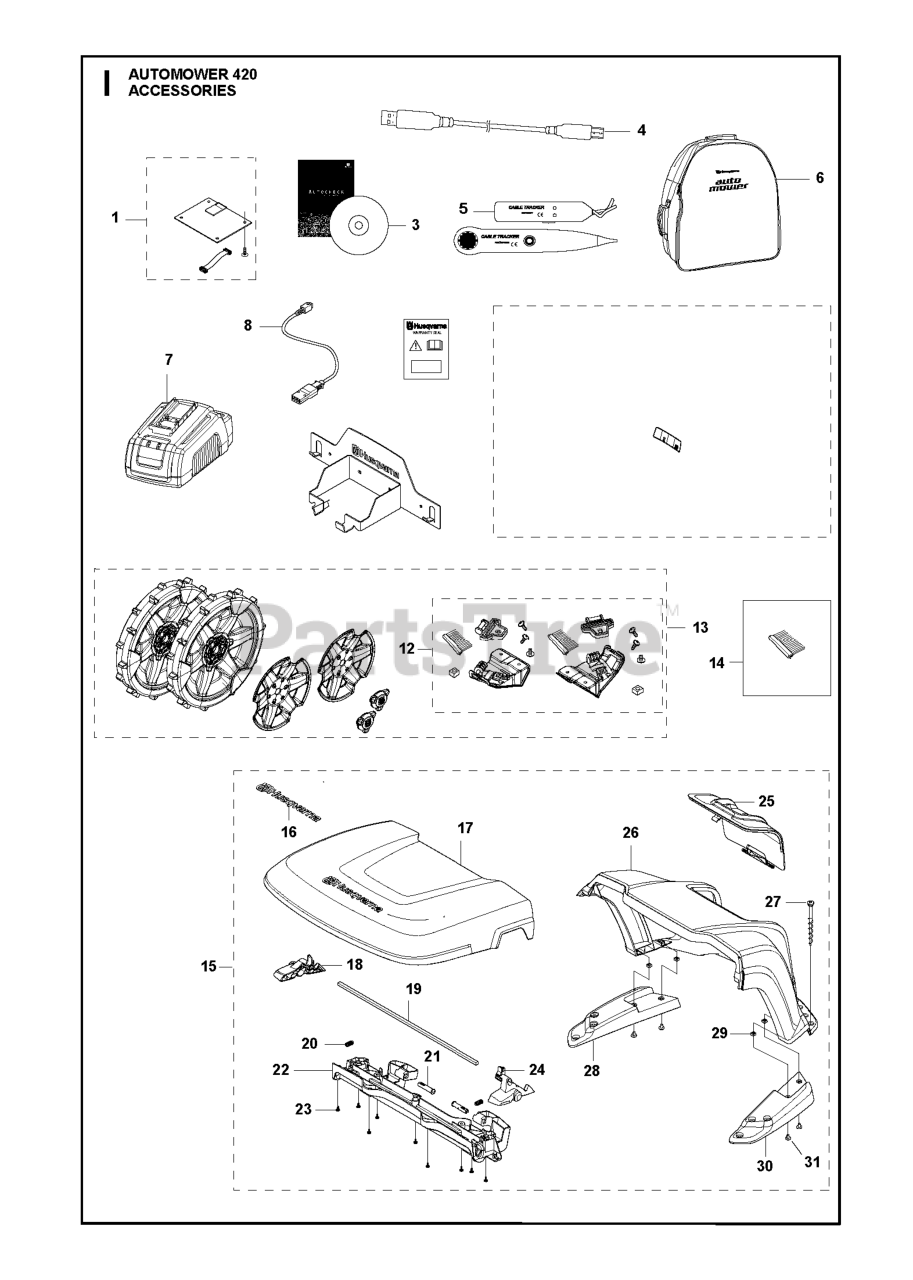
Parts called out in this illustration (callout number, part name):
1	CONNECT MODULE 315 / 430X
3	DVD AUTOCHECK EXP SERVICE
4	CABLE WHITE ALT GREY
5	TEST EQUIPMENT
6	BAG
7	CHARGER BATTERY TEST
8	CABLE ASSY QUICK CHARGER
9	LABEL WARRANTY SEAL DEALER
10	MISC. BLISTER WALL HANGER
12	BRUSH KIT 430/450
13	REAR WHEEL KIT W/ BRUSHES
14	WHEEL BRUSH REFILL KIT
15	430/450 HOUSE KIT
16	DECAL.HUSQVARNA.210MM
17	KIT LID - AUTOMOWER HOUSE
18	HANDLE RELEASE LEFT
19	ROD
20	SPRING SPRING CAP
21	HINGE PIN
22	BEAM
23	SCREW 14MM
24	HANDLE RELEASE RIGHT
25	HATCH
26	COVER BASE P2 HOUSE
27	SCREW KIT CS
28	SUPPORT BASE LEFT
29	NUT
30	SUPPORT BASE RIGHT
31	SCREW IHPANM M6X25 4.6 ZP-BC
